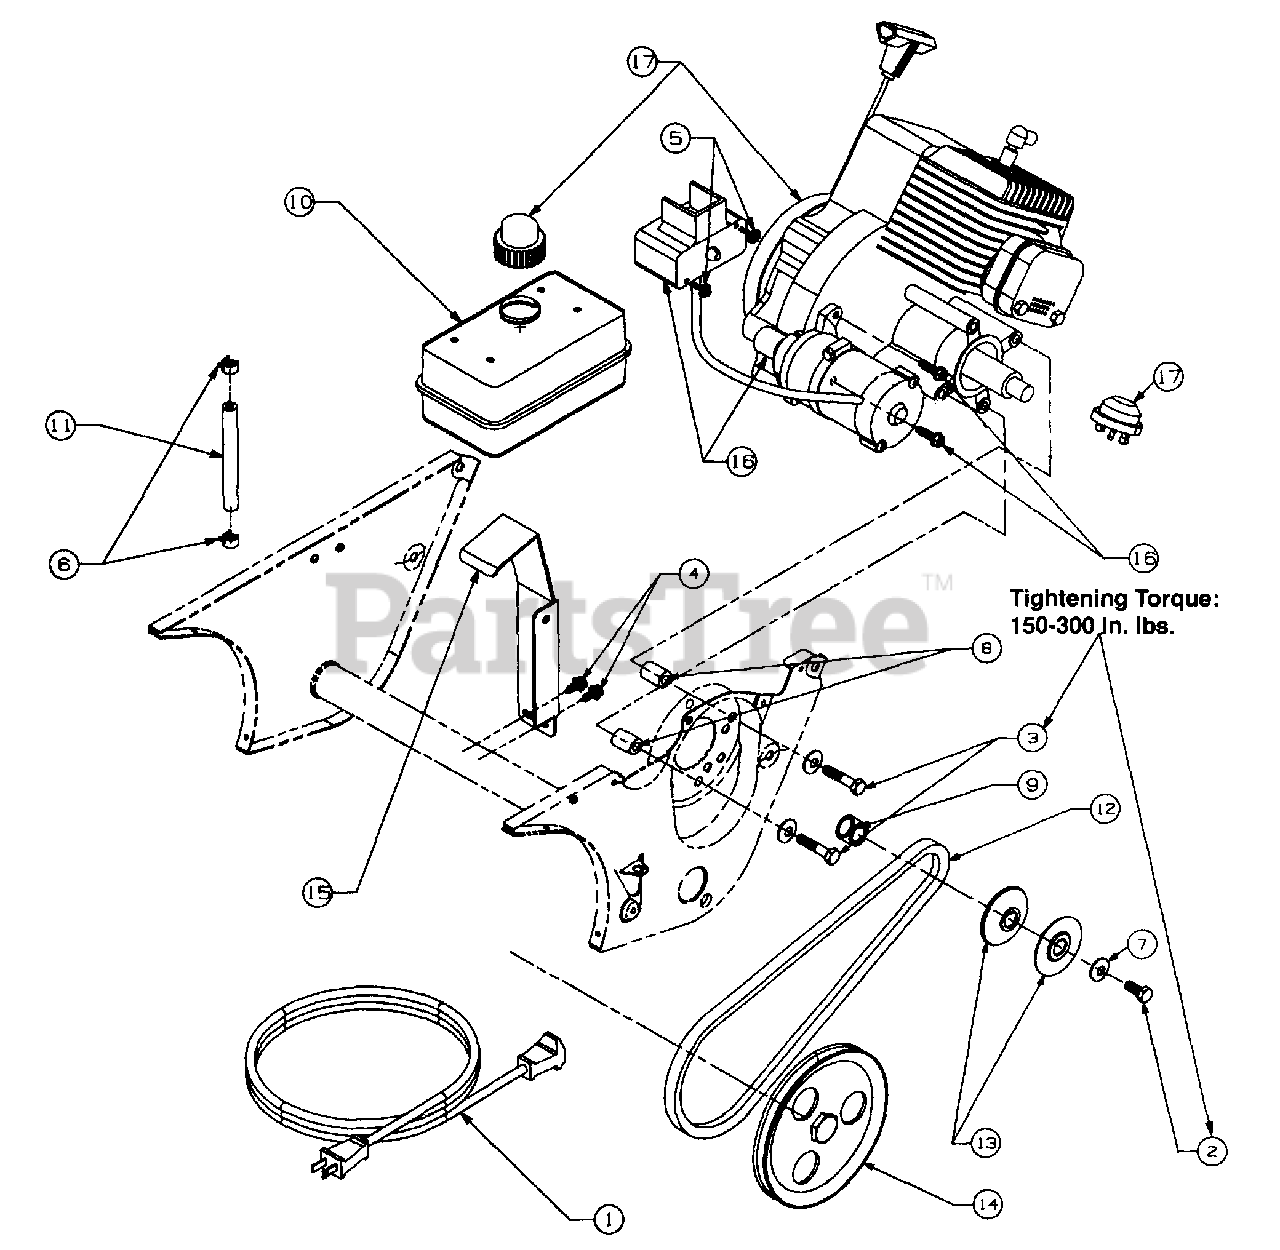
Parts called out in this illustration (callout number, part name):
1	Cord - Extension 110V3M 2 Prong
2	Screw - Hex Cap
3	Screw - Hex Cap
4	Screw - Washer
5	Screw - Hex
6	Hose Clamp
7	Washer - Bell
8	Spacer
9	Spacer
10	Tank - Fuel 1 Qt.
11	Hose - Fuel 12"
12	V-Belt
13	V-Pulley Half
14	Pulley
